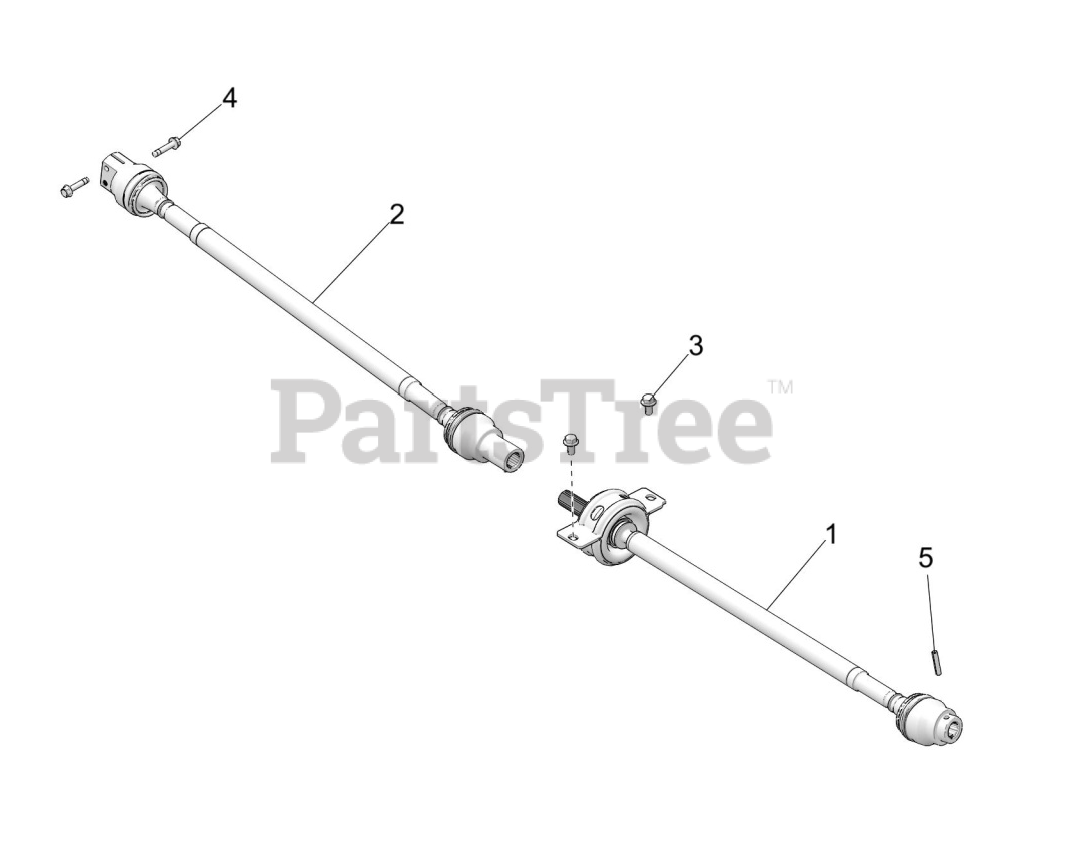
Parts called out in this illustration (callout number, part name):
1	ASM-PROPSHAFT,FRONT
2	ASM-PROPSHAFT,REAR
3	BOLT-M10X1.5X20,HXFLG,W/PATCH
4	SCR-HXFL-M8X1.25X40 8.8 ZODP30
5	PIN,SPRING(10)
